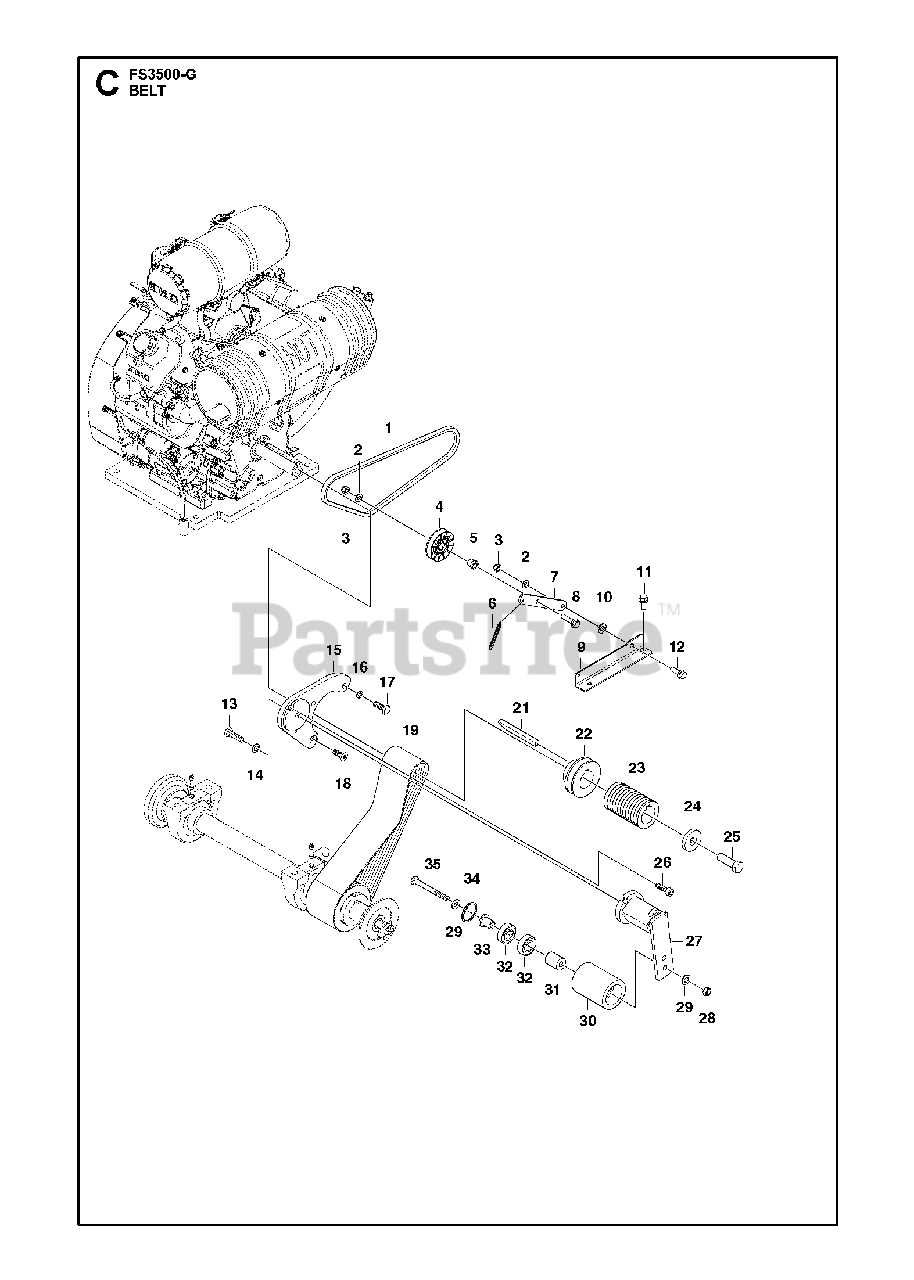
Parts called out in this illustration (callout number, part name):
2	WASHER
3	HEXAGON LOCKING NUT
10	WASHER
16	WASHER
29	WASHER
